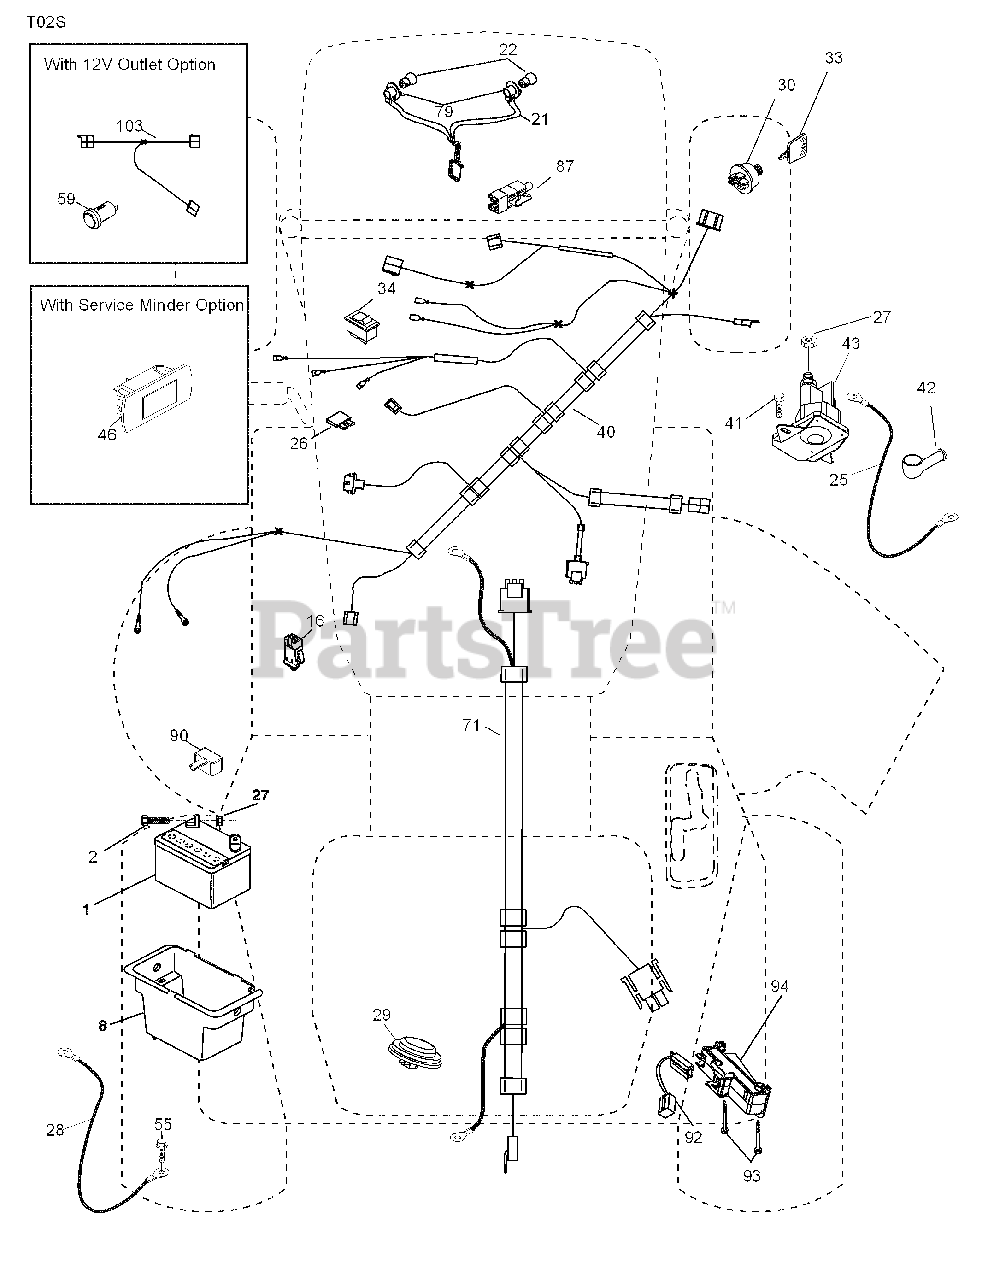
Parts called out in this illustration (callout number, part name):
2	Bolt Hex Hd 1/4-20 unc x 3/4
8	Box Battery
16	Switch Interlock
21	Harness Socket Light
22	Bulb, Light #1156
25	Cable Battery 6 Ga. Red 14.5
26	Fuse
27	Nut Keps Hex 1/4-20 unc
28	Cable Ground 18" Rear Battery Blk 6 Ga.
29	Switch Seat
30	Switch Ign
33	Key/Chain
34	Switch Light/Reset
40	Harness Ign
41	Screw 1/4-20 unc x 1/2
42	Cover Terminal Red
43	Solenoid
55	Screw 5/16-18 x 3/4
71	Harness Ign. Chass.
79	Socket Asm. Bulb Twistlock
87	Switch Interlock Clutch Cable
90	Cover Terminal
92	Harness Pigtail Console ROS
93	Screw Plastic 10-14 x 2.0
94	Modual Reverse ROS
